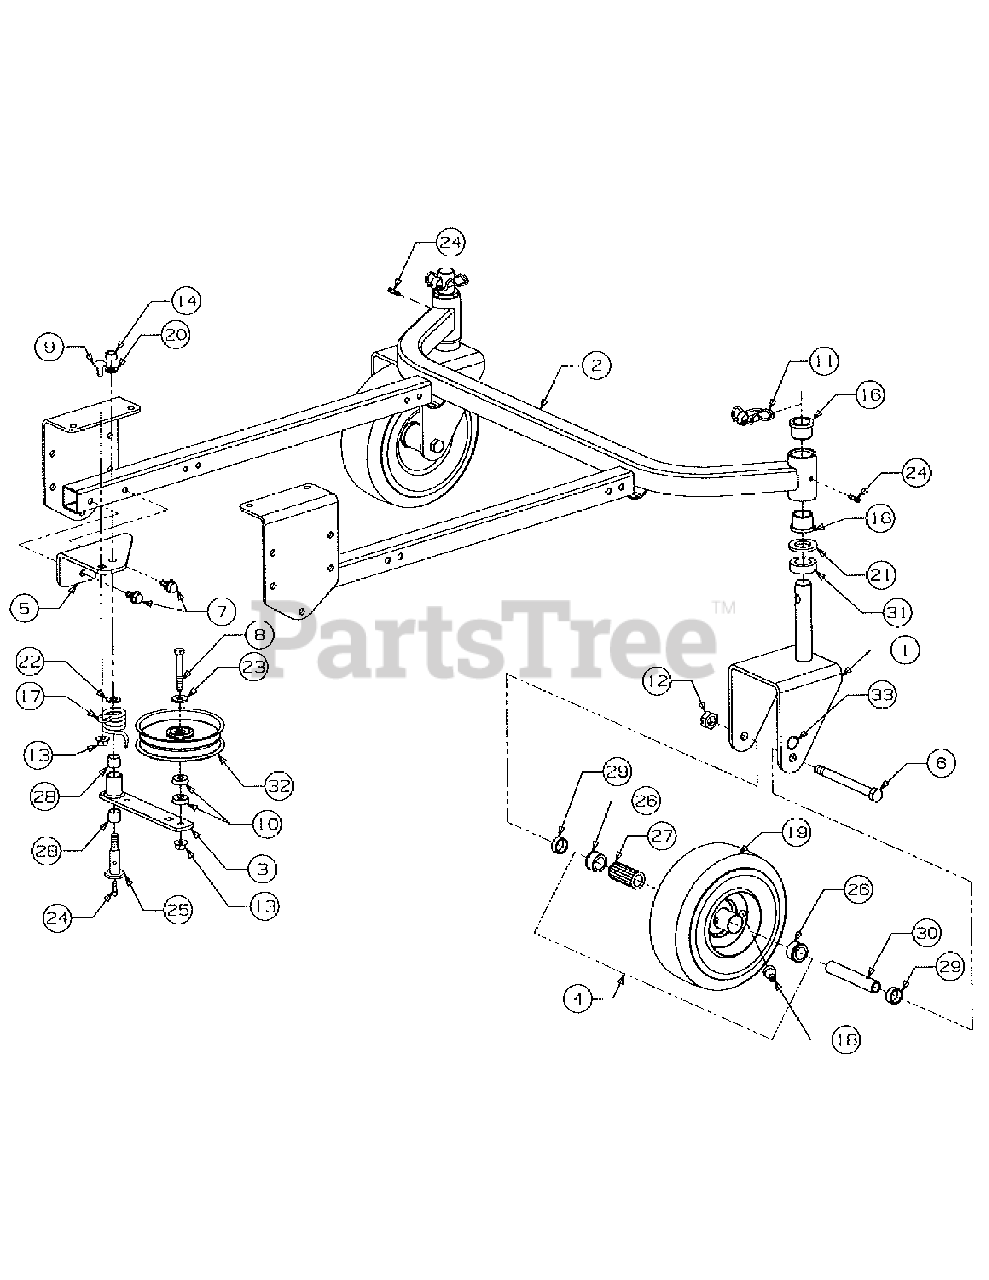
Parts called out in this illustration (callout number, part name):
2	Cradle Ass'y. Fixed
2	Bolt, Sht Nk Carriage, 3/8-16 x .75 Gr5
2	Nut, Hex Flanged Lock, 3/8-16
3	Arm. Ass'y, Idler
4	Wheel Ass'y, Caster
5	Bracket, Idler Arm
6	Screw, Hex Cap, 1/2-20 x 5.50
7	Screw, Hex Wash Sf Tap, 3/8-16 x .75
8	Screw, Hex Cap, 3/8-16 x2.50 Gr 5
9	Boltm ShtNk Carriage, 3/8-16 x .75 Gr 5
10	Spacer, .380 x 1.00 x .32
11	Pin, Klik
12	Nut, Hex Center Lock, 1/2-20
13	Nut, Hex Flanged Lock, 3/8-16
14	Nut, Hex, 7/16-14 Gr 5
16	Bearing, Flange
17	Spring, Torsion
18	Valve, Tubeless
19	Tire, Smooth, 9.0 x 3.50 x 4
20	Washer, Lock, 7/16
21	Washer, Special
22	Washer, Flat, .469 x .875 x .105 Thk
23	Washer, Flat, .406 x 1.00 x .105 Thk
24	Fitting, Lube
25	Bolt, Shoulder
26	Bearing, Graf Oil Flange
27	Bearing, Roller
28	Bearing, Sleeve
29	Spacer, .790 ID x .347
30	Spacer. Wheel
31	Spacer, 1.015 x 1.62 x.50
32	Pulley, Flat Idler, 5''
33	Label, Inflation
